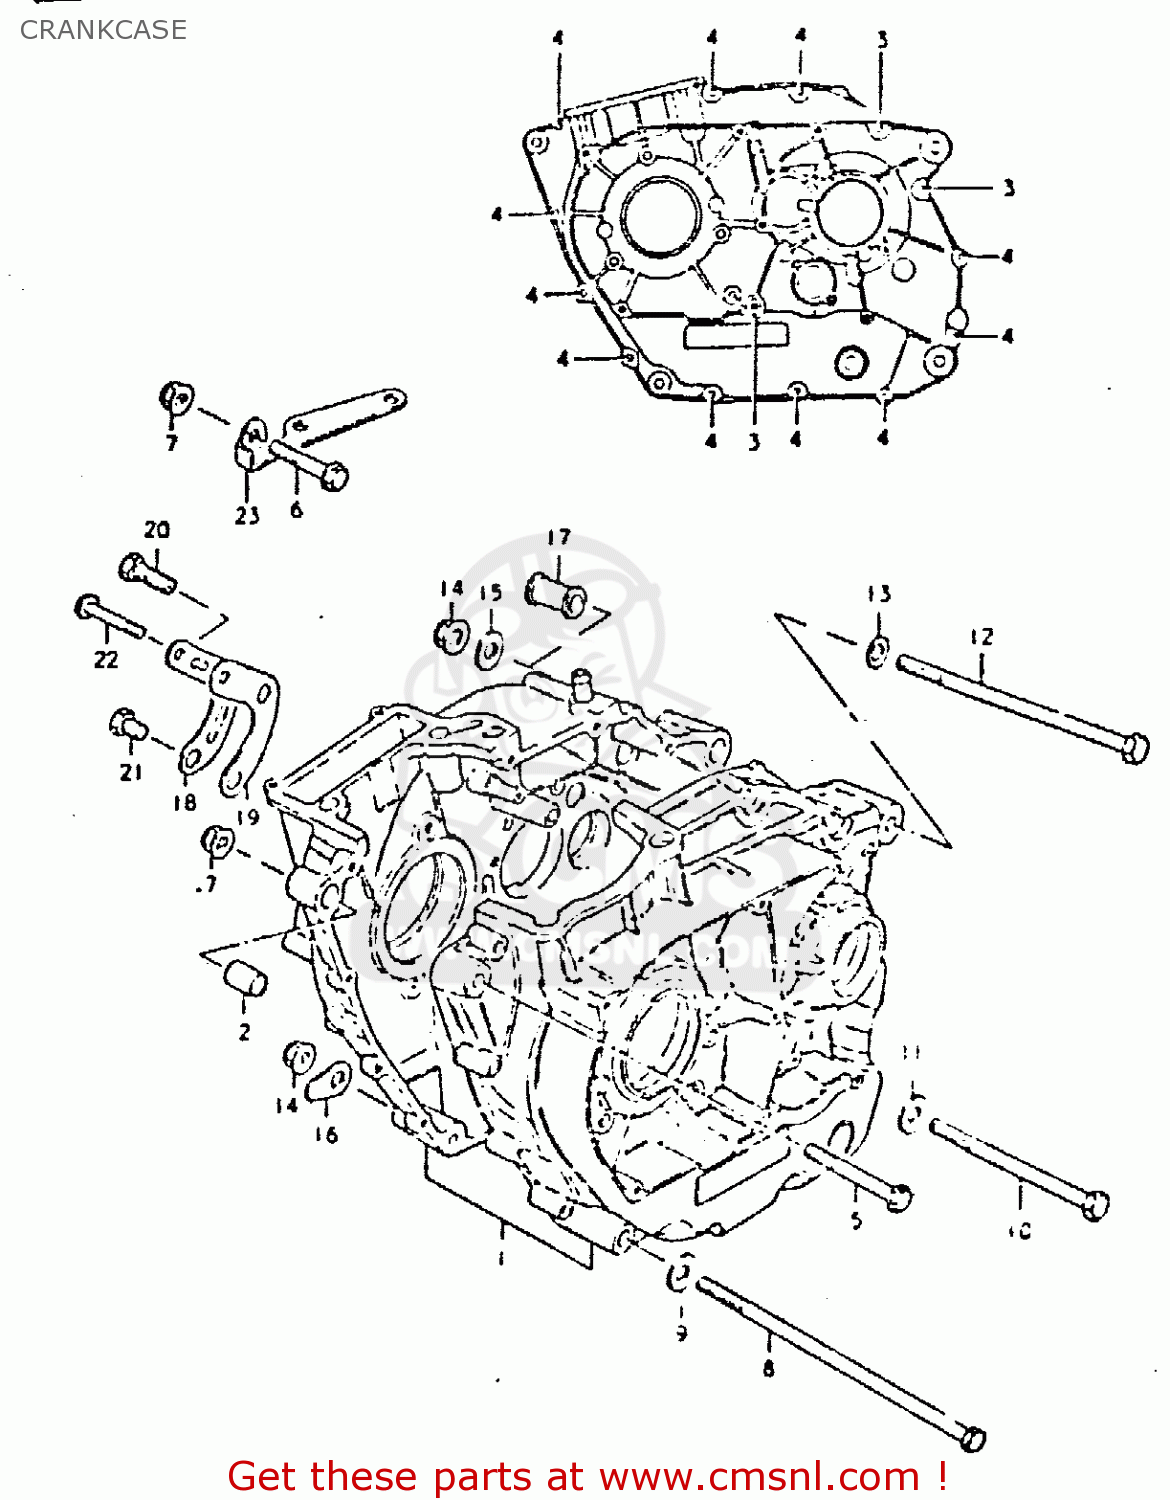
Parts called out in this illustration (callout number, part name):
1	CRANKCASE SET
2	PIN
3	SCREW
4	SCREW (6X35)
5	BOLT (8X70)
6	BOLT
7	NUT
8	BOLT(10X190)
9	WASHER
10	BOLT 10X115
11	WASHER(10.5X20X3.2)
12	BOLT 10X155
13	WASHER
14	NUT
15	WASHER(10.5X20X3.2)
16	WASHER
17	SPACER
18	CAP,OIL GALLERY
19	GASKET,OIL GALLERY (MCA)
20	BOLT,UNION
21	PLUG
22	BOLT
23	PIPE,CYLINDER HEAD OIL
